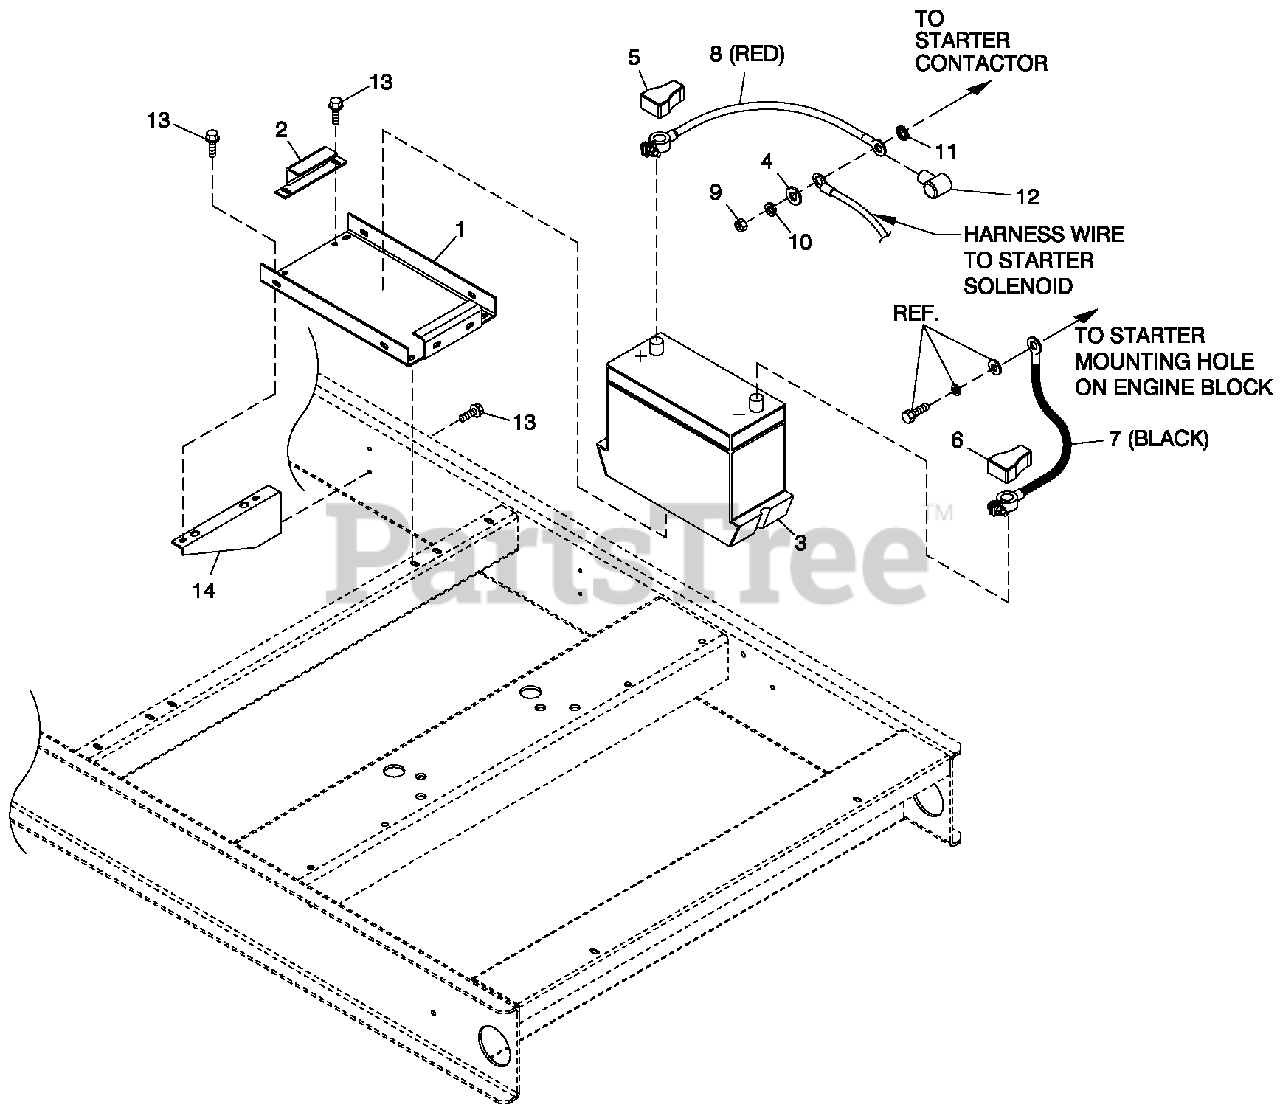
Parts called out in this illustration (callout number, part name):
1	TRAY BATTERY
2	STRAP BATTERY RETAINMENT
3	BATT12VDC 24F 625
4	WASHER FLAT 3/8-M10 ZINC
5	BATT POST COVER RED +
6	BATT POST COVER BLK -
7	CABLE BATT BLK #1X18.00
8	CABLE BATT RED #1X28.00
9	NUT HEX M8-1.25 G8 YEL CHR
10	WASHER LOCK M8-5/16
11	WASHER SHAKEPROOF EXT 5/16 STL
12	BOOT BATTERY CABLE
13	SCREW THF M6-1X16 N WA Z/JS
14	SUPPORT BATTERY TRAY
